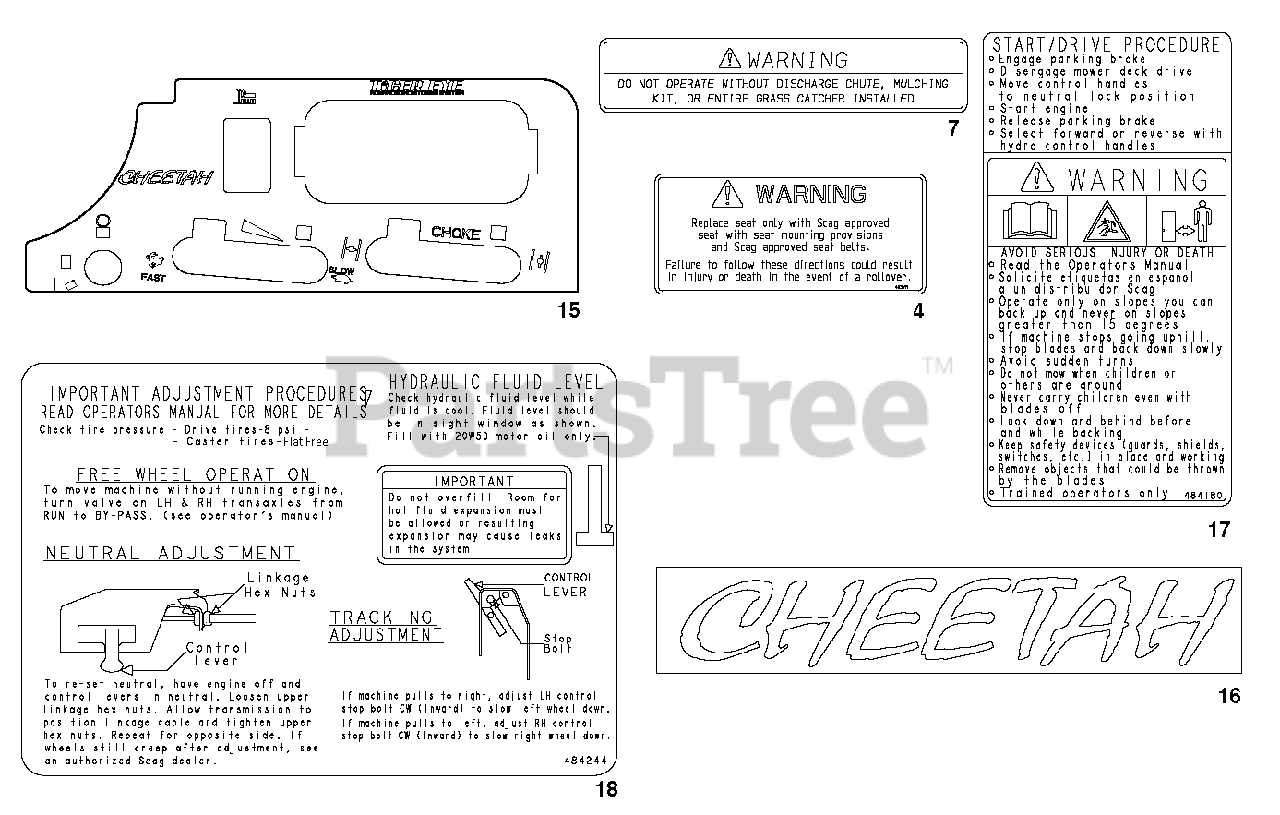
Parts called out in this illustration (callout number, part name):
4	Decal, Seat Replacement
7	Decal, Warning
15	Decal, Instrument Panel - SCZ
16	Decal, Cheetah
17	Decal, Start / Drive
18	Decal, Adjustments - SCZ
